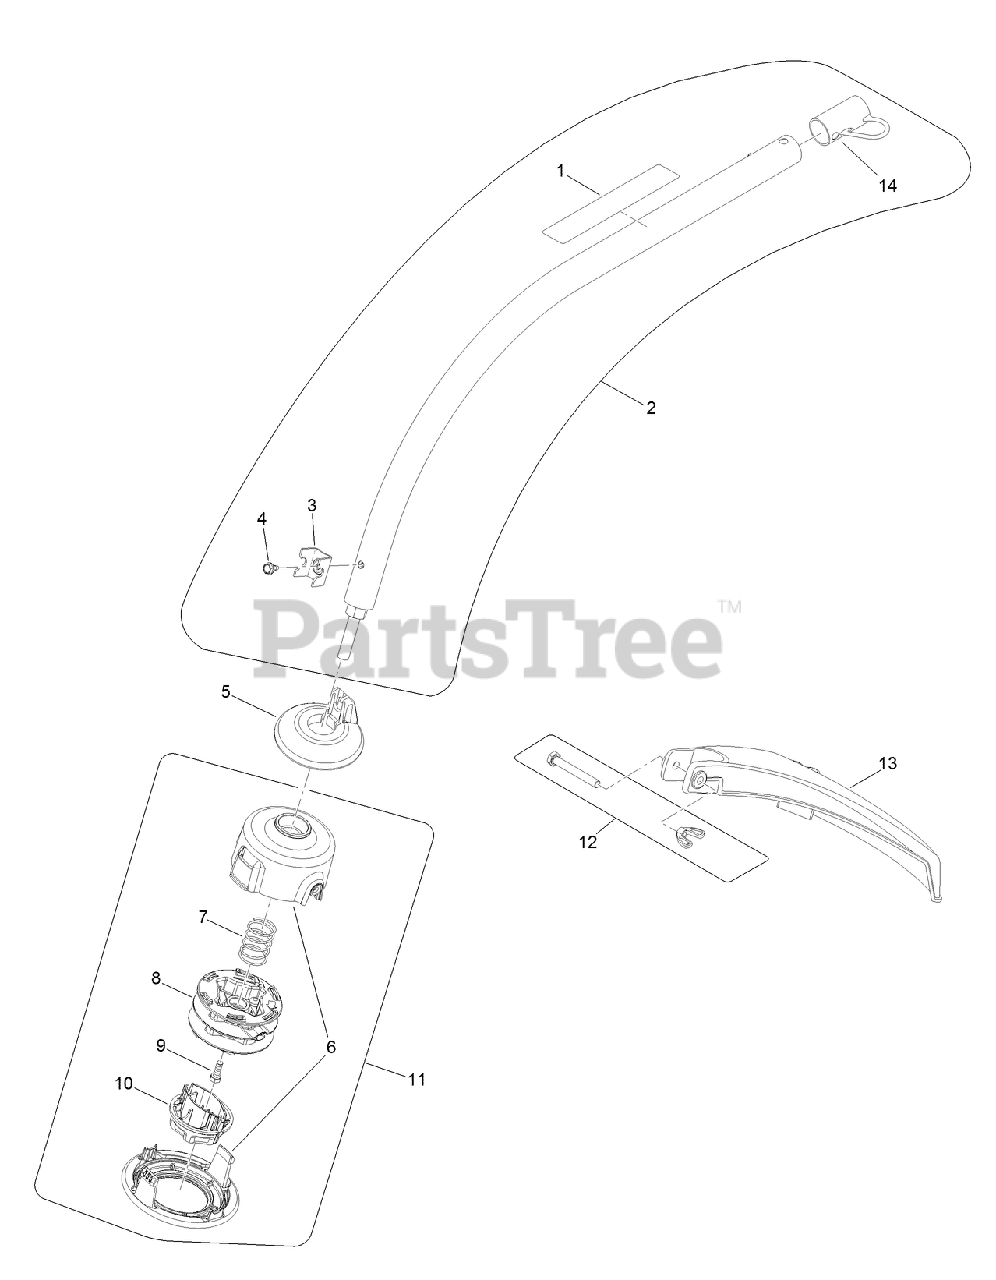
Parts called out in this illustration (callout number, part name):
1	DECAL-WARNING
2	SHAFT ASM
4	SCREW-HWH
5	SHIELD-GRASS
6	HOUSING-STRINGHEAD
7	SPRING-COMPRESSION
8	SPOOL ASM
10	KNOB-BUMP
11	SPOOL HEAD ASM
12	HARDWARE KIT
13	GUARD-SHIELD, GRASS
14	CAP-HANGER
